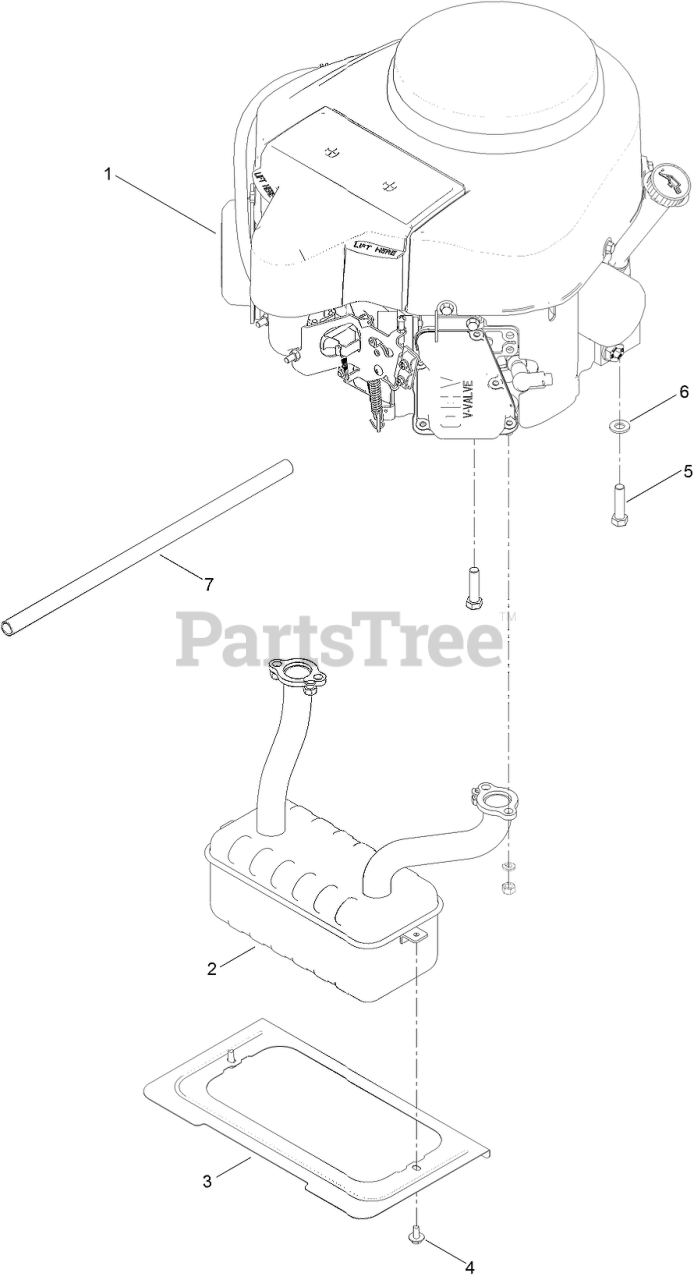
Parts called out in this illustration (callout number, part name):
2	MUFFLER
3	SHIELD-HEAT
4	SCREW-HHFTF
5	BOLT-HH
6	WASHER-FLAT
7	TUBE-DRAIN, OIL
